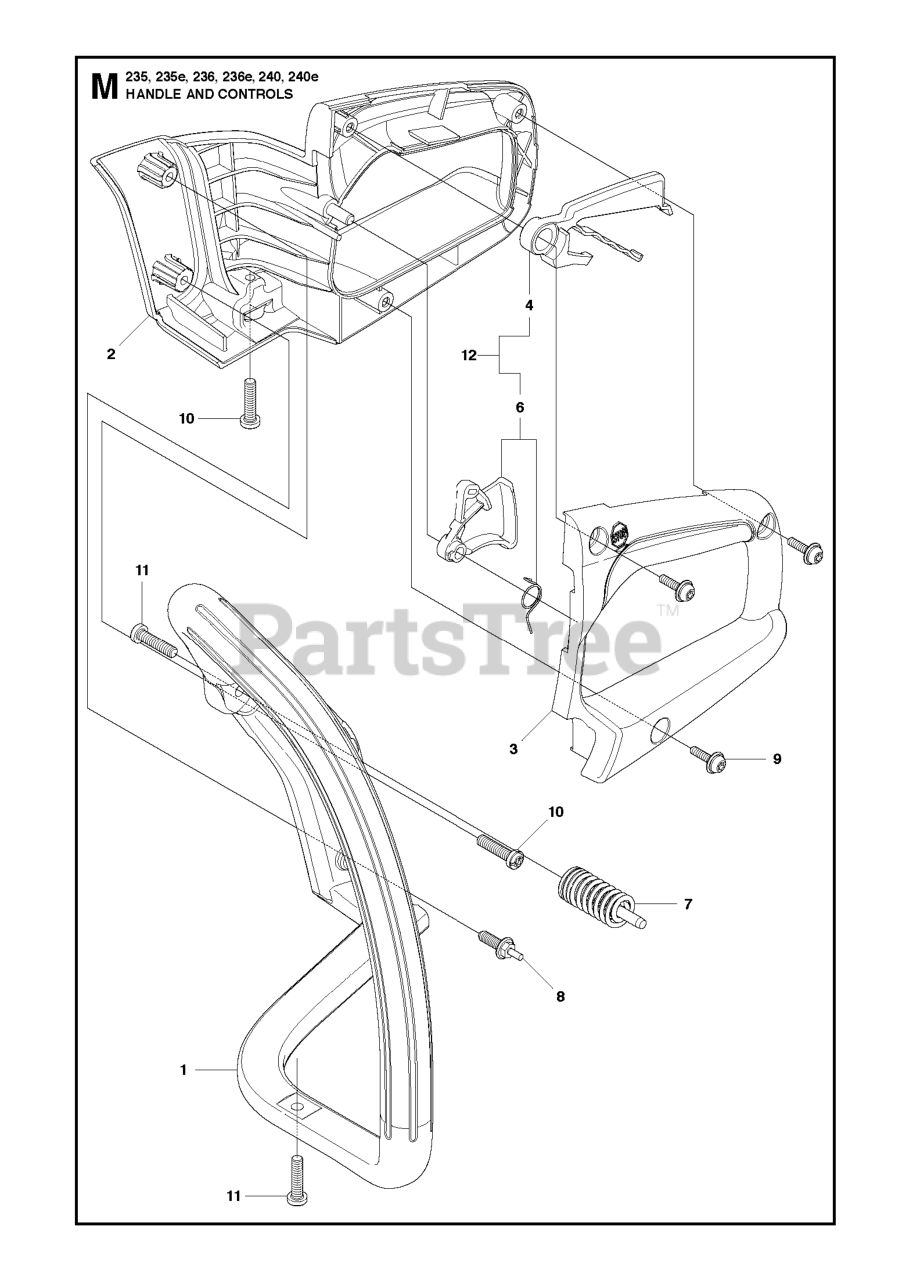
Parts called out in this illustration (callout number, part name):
1	FRONT HANDLE
2	REAR HANDLE
3	REAR HANDLE COVER
3	COVER REAR HANDLE
4	LOCKOUT - THROTTLE
6	ASSY TRIGGER GRAY
7	SPRING CYLINDER ASSY
10	SCREW FILTER PLATE
11	SCREW M5.38-14X22.225MM
12	TRIGGER & LOCKOUT KIT
